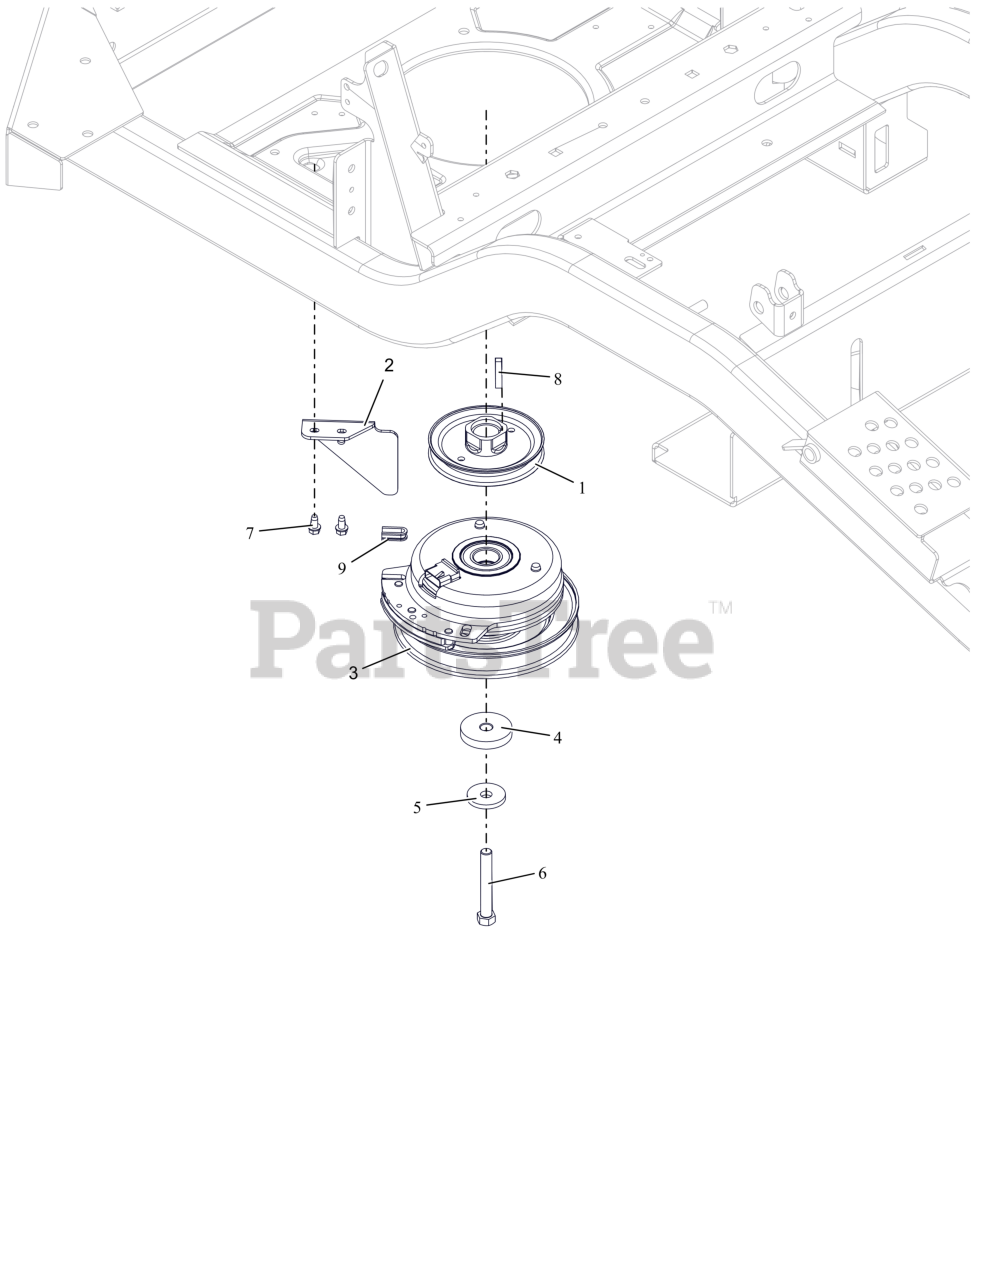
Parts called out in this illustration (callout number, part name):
1	PULLEY, 4.50 OD X 1.003 ENGINE
2	BRKT- CLUTCH STOP
3	CLUTCH, WARNER 1.00 HD,PTZ
4	SPACER, .474/.459X2.00X.350
5	WASHER, 7/16" SPRING DISK
6	BLT, HEX .44-20X3.00 G8 ZCC NT
7	SCR-TAP .25-20X.50 HWH ZCC
8	KEY-SQ .25 X 1.25 X .25 SAE
9	BSHG, CLUTCH
